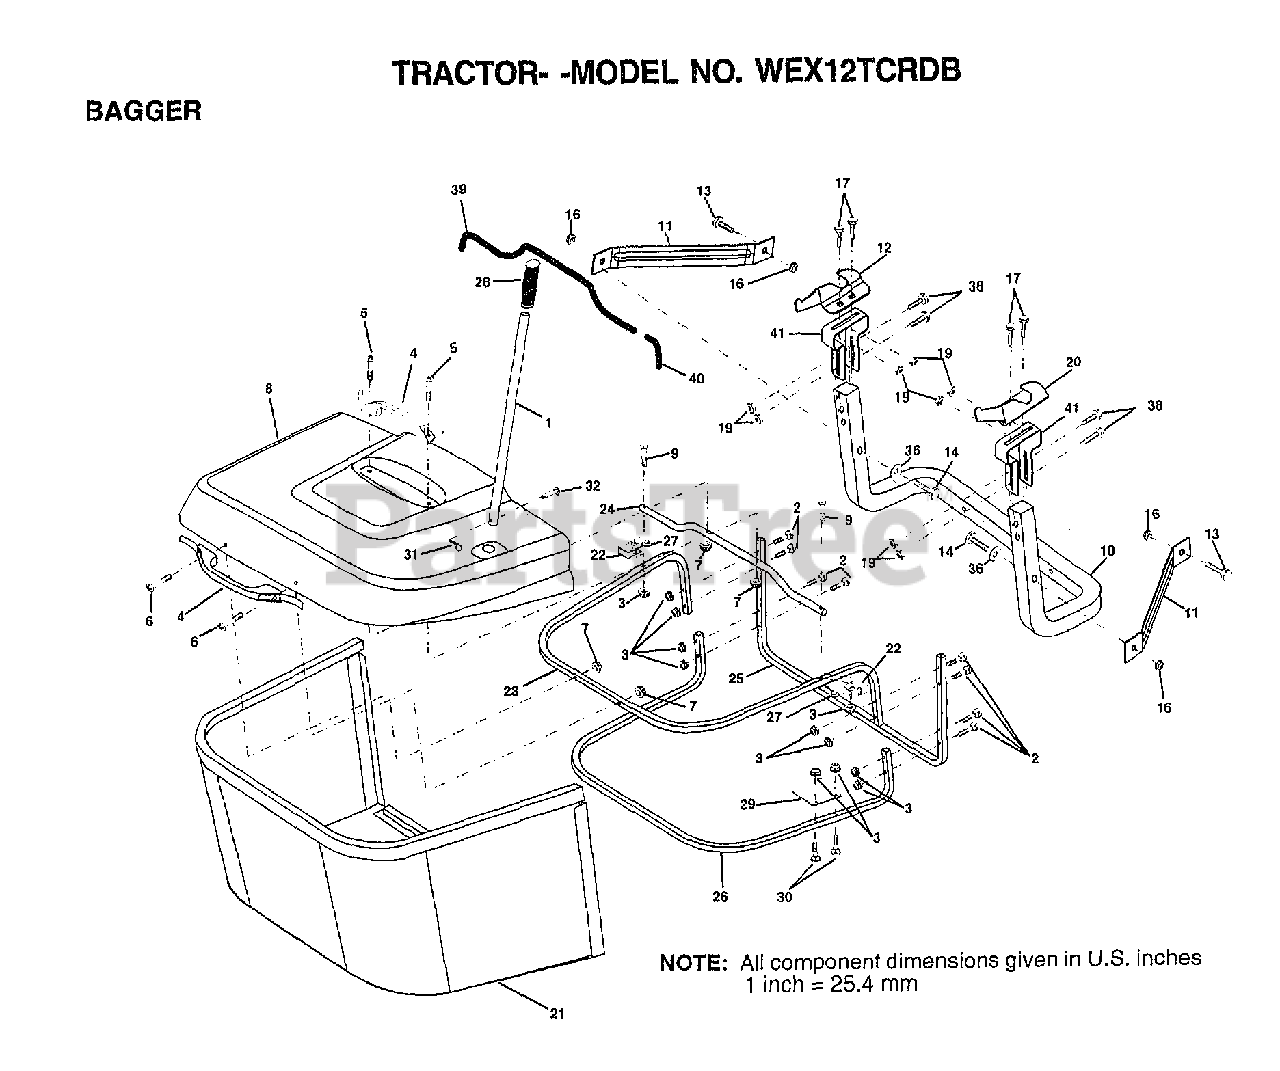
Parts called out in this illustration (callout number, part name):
1	TUBE.HDLE.BAG.CRD
2	BOLT.CARRIAGE.1/4-20X2.0
4	HANDLE BAGGER
5	"SCREW,PAN.HEAD"
7	NUT.WIZ.LOCK
8	COVER.BAGGER.CRD
9	BOLT CARRIAGE
10	TUBE SUPPORT BAGGER CRD
11	BRKT.SUPT.UPPER.BAG.CRD
12	BRACKET HORIZ ADJ BGGR LH CRD
13	BOLT
14	BOLT.HEX.3/8-16X2-1/2
17	BOLT
19	NUT
20	BRACKET HORIZ ADJ BGGR RH CRD
21	BAG.ASM.CRD
22	BRKT.SIDE.BAG.CRD
23	TUBE.UPPER.BAG.CRD
24	TUBE.PIVOT.BAG.CRD
25	TUBE.FT.BAG.CRD
26	TUBE.LOWER.BAG.CRD.
27	BUSHING SNAP BAGGER CRD
28	GRIP.HANDLE.BLACK
29	PLATE.STOP.BAG.HDLE.CRD
30	BOLT.CARRIAGE
31	RETAINER M
32	RIVET.DRILL.1.75
38	BOLT.5/16-18X2.5
41	BRACKET VERT ADJ BAGGER CRD
